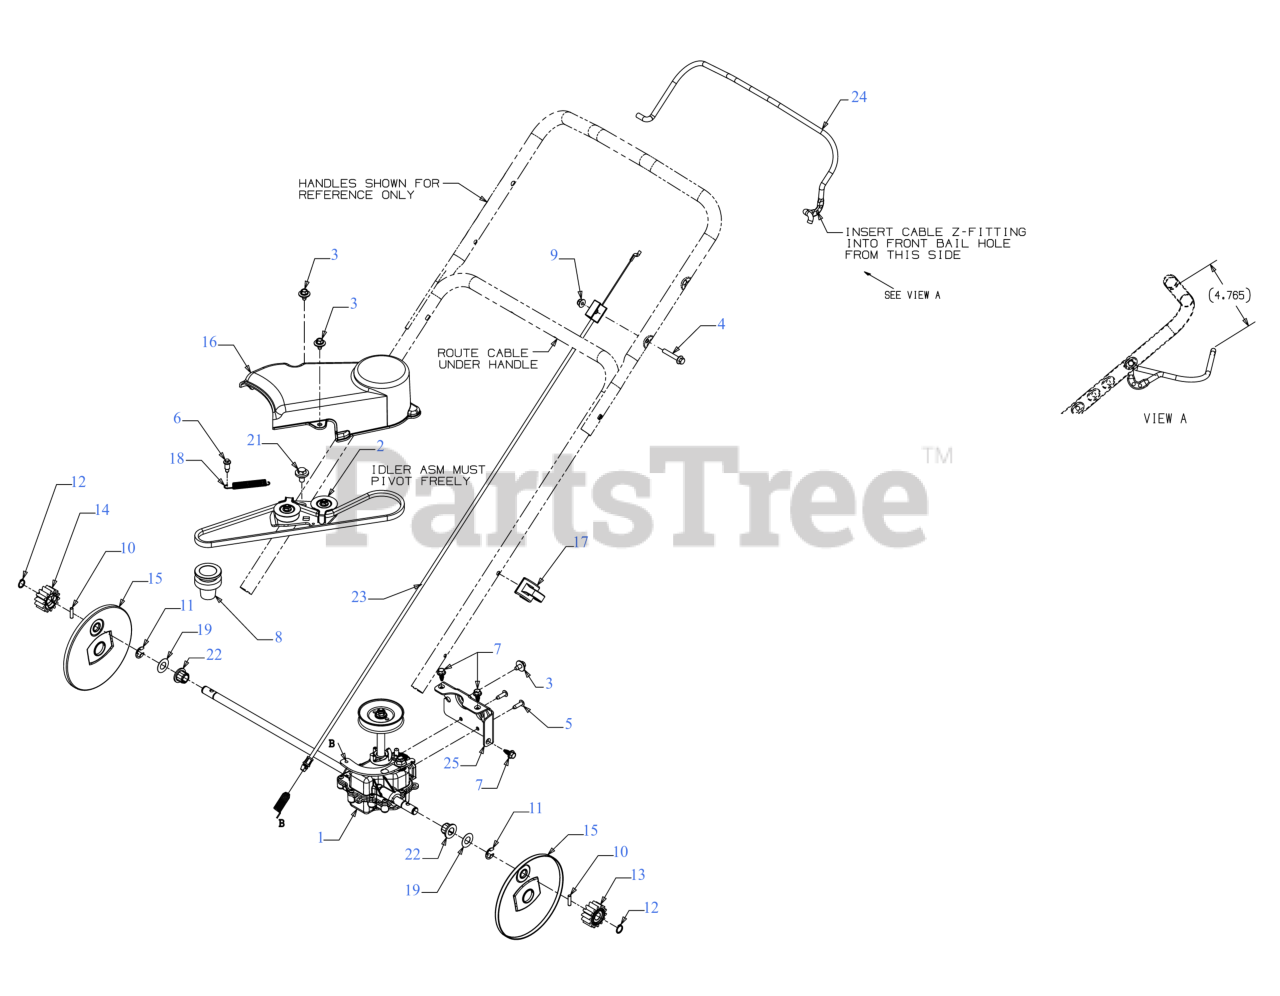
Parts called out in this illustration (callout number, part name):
1	TRANSMISSION
2	IDLER ASSEMBLY (COMPONENTS)
3	SCREW 1/4-20 x .50
4	SCREW 1/4-20 x 1.50 GR5
5	SCREW #12-16 x .750
6	SCREW .30 x .46
7	SCREW 1/4-20X.625
8	IMPELLER INSERT HUB
9	FLANGE LOCK NUT
10	DOWEL PIN
11	E-RING FOR .500 SHAFT
12	SNAP RING FOR .500
13	SPUR GEAR 14T (LH)
14	SPUR GEAR 14T (RH)
15	DUST WHEEL COVER
16	BELT COVER
17	CABLE GUIDE
18	EXTENSION SPRING
19	FLAT WASHER
21	SHOULDER SCREW .560X.165: 5/16-18
22	HEX FLANGE BEARING .506ID x .590LG
23	CONTROL CABLE
24	GULLWING DRIVE BAIL- RED
25	MOUNTING BRACKET
